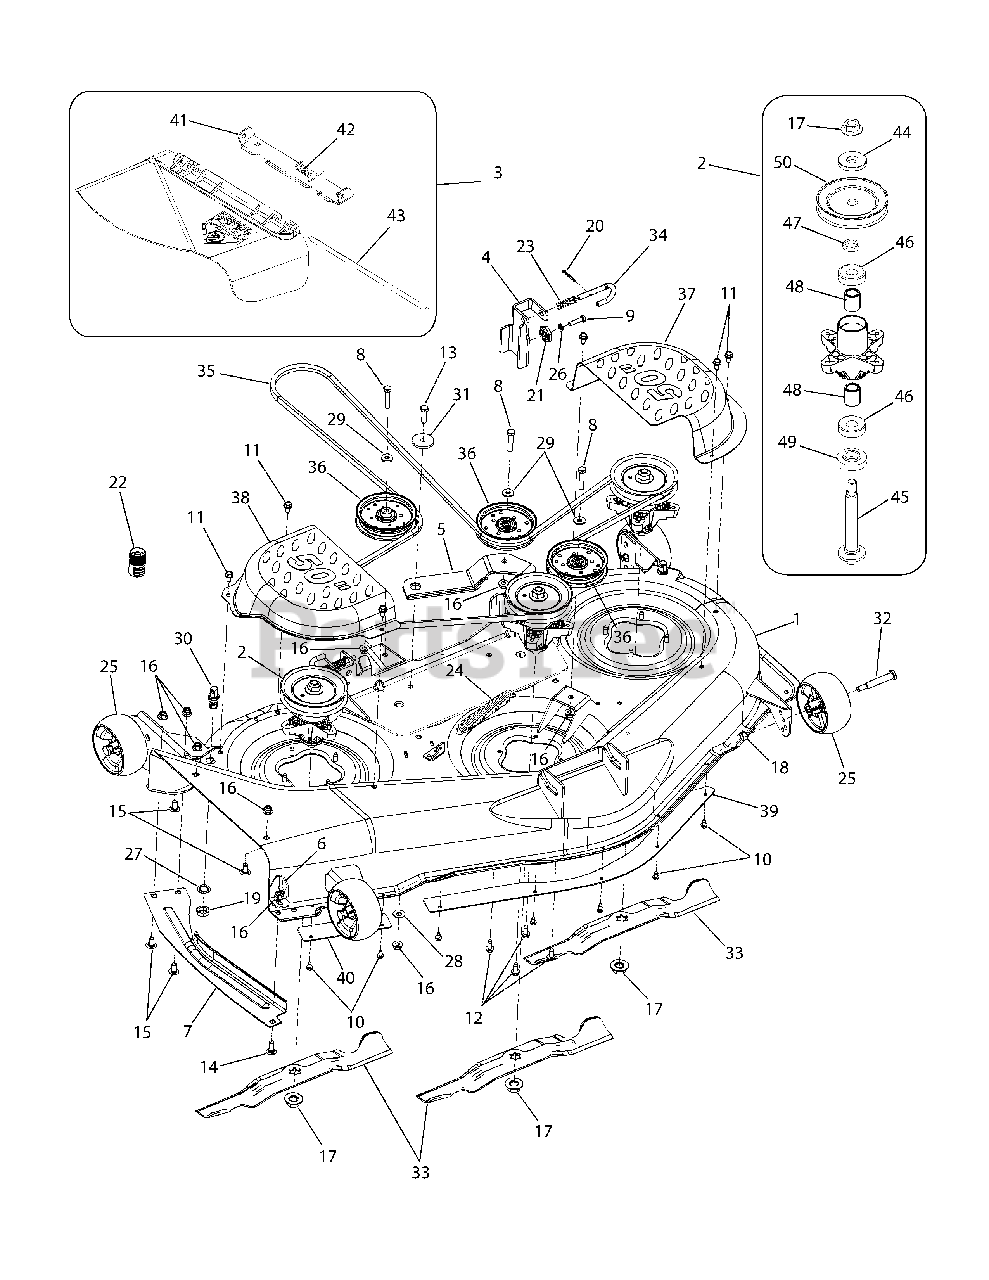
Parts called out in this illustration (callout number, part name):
2	Spindle Assembly
3	Chute Assembly, Discharge
8	Screw, Hex Cap, 3/8-16 x 1.75 GR5
9	Screw, Hex Cap, 5/16-18 x 1.25 GR5
10	Screw, Hex Wash. Hd. Tapp,1/4-20 x .5
11	Screw, Hex Wash. Hd. Tapp, 5/16-12 x .75
12	Screw, Hex Wash. Hd. Tapp, 5/16-18 x .75
13	Screw, Hex Cap, 3/8-16 x 1.25 GR5
14	Screw, Carriage, 3/8-16 x 1.0
15	Screw, Carriage, 3/8-16 x .75
16	Nut, Hx Insert Flange Lck, 3/6-16 GrF
17	Nut, Hex Flange, 5/8-18
18	Nut, Hex Flange Lock, 3/8-16 GRF
19	Nut, Hex, M16-1.5
20	Pin, Cotter, 1/8 x 1.25
21	Gear, Deck Adjustment
22	Adapter, Water Nozzle
23	Spring, Compression
24	Spring, Extension, .94 Dia. x 6.74
25	Wheel, Deck Ball, 5.0
26	Washer, Lock, 5/16
27	Washer, Bell, .45 x 1.0 x .062
28	Washer, Internal Tooth Lock, 5/8
29	Washer, Flat, .38 x .93 x .110 HT
30	Nozzle, Deck Wash
31	Spacer, Shoulder, .884 x .190
32	Screw, Shoulder, .5 x 2.5:3/8-16
33	Blade, 2 in 1, 17.9 Lg
34	Rod, Deck Hanger
35	Belt V, Type A Sec x 134
36	Pulley, Idler, 4.25 Dia
41	Bracket, Chute Mounting
42	Spring, Torsion
43	Pin, Hinge
44	Washer, Flat, .76 x 1.50 x .12
45	Shaft, Spindle, 5.75
46	Bearing, Ball
47	Spacer, .79 x 1.25 x .175
48	Spacer, .80 x 1.10 x 1.32
49	Spacer, .79 x 1.82 x .55
50	Pulley, V Type, 5.39
